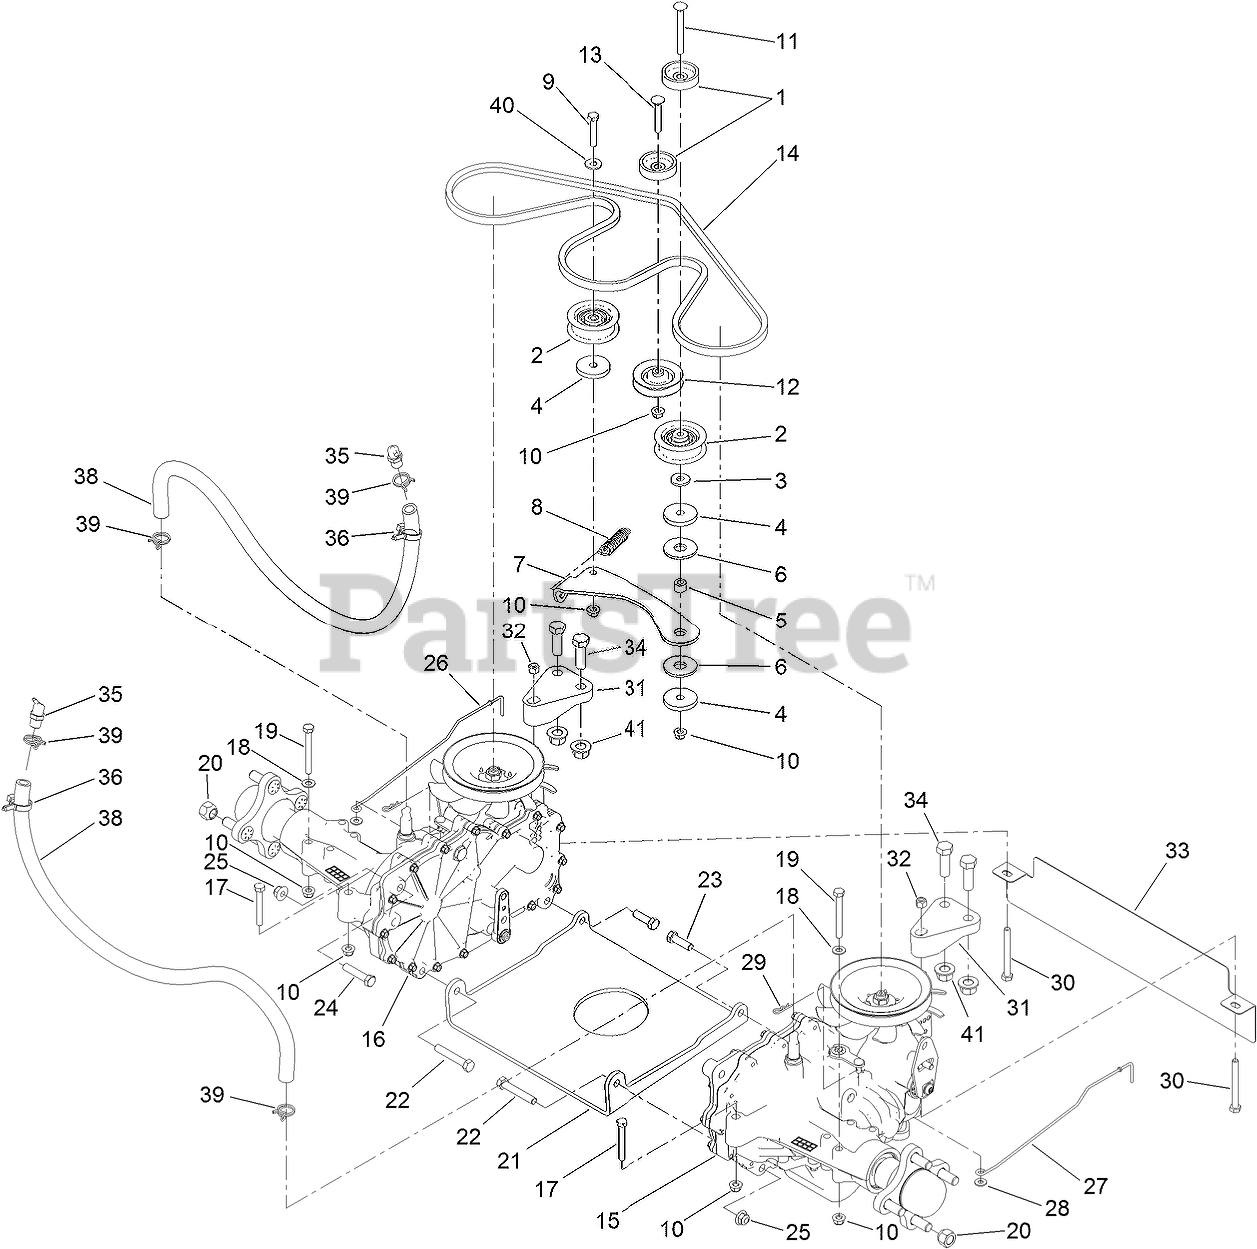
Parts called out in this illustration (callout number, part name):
1	SPACER
2	PULLEY-IDLER
3	WASHER
4	WASHER-PLAIN
5	BUSHING
6	WASHER-FRICTION, COMPOSITE
7	ARM-IDLER
8	SPRING-RETURN, PEDAL
9	SCREW-HH
10	NUT-HF, NI
11	SCREW-CARR
12	PULLEY-IDLER
13	Screw-CARR
14	V-BELT
15	LH HYDRO TRANSMISSION ASM
16	RH HYDRO TRANSMISSION ASM
17	SCREW-HH
18	WASHER-PLAIN
19	SCREW-HH
20	NUT-LUG
21	PLATE-CROSS, HYDRO
22	SCREW-HH
23	SCREW-HH
24	SCREW-HH
25	NUT-HF, NI
26	ROD BYPASS, RH
27	ROD BYPASS, LH
28	WASHER-FLAT
29	PIN-COTTER
30	SCREW-HH
31	SUPPORT-HYDRO, REAR
32	NUT-LOCK, NI
33	GUARD REAR, WIDE
34	SCREW-HH
35	BREATHER KIT
36	CLAMP-HOSE
38	HOSE-HYDRO
39	CLAMP-HOSE
40	WASHER-FLAT
41	NUT-LOCK
